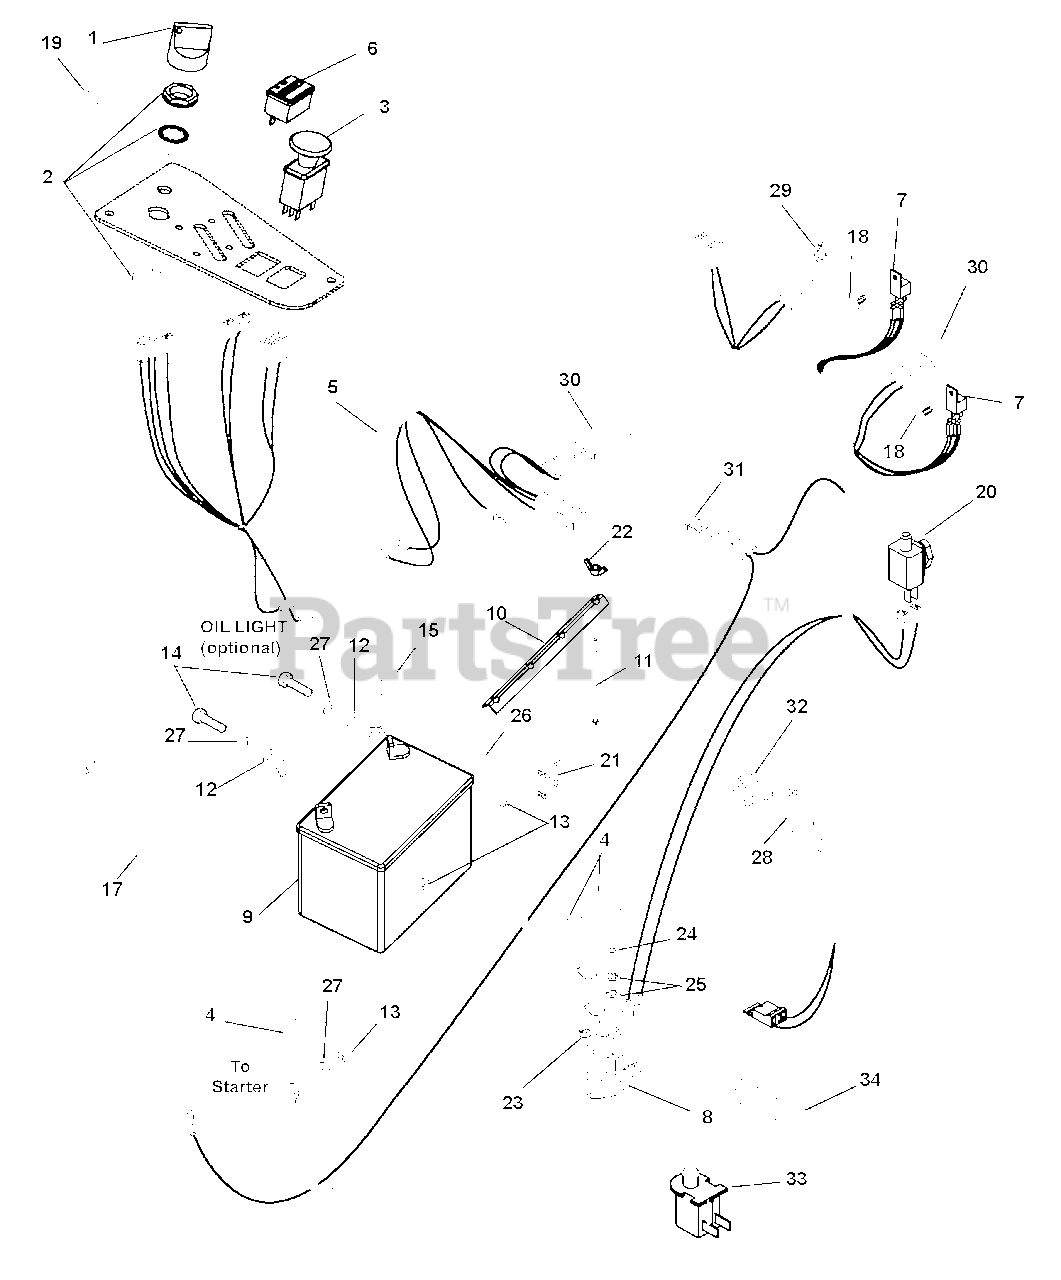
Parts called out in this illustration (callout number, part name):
1	Key with Shield
2	Switch, Ignition
3	Switch, Clutch
4	Boot, Eyelet Terminal
5	Harness Wire
6	Hour Meter with Maintenance
7	Relay, Sealed with Diode
8	Solenoid
10	Hold Down
11	Bolt, Round Head Square Neck .25-20 x 7.50
12	Washer, Flat Steel .281 x .620 x .065
13	Nut, Hex .25-20
14	Bolt, Hex .25-20 x .75 Grade 5
15	Insulator
16	Cable, Positive Battery 9.00"
17	Cable, Negative Battery
18	Rivet, .25 Nylon Panel
19	Plug, Hole .50 Diameter
20	Switch, Single Pole (N.O.) – Brake Switch
21	Bushing, Panel Snap .687 x .875 x .56
22	Nut, Locking Wing .25-20
23	Screw, Tapping .25-20 x .50 Hex Washer Head
24	Nut, Jam .31-24
25	Washer, Star Washer .31 x .078 Regular
26	Cable, Starter
27	Washer, Lock .25 x .062
28	Tie, Cable LG 5.50
29	Fuse 20 Amp
30	Diode, Connector Shell
31	Fuse, 25 Amp
32	Clip,T .31-.38
33	Switch, Snap Mounting N.O.
34	Harness, Adapter Clutch
